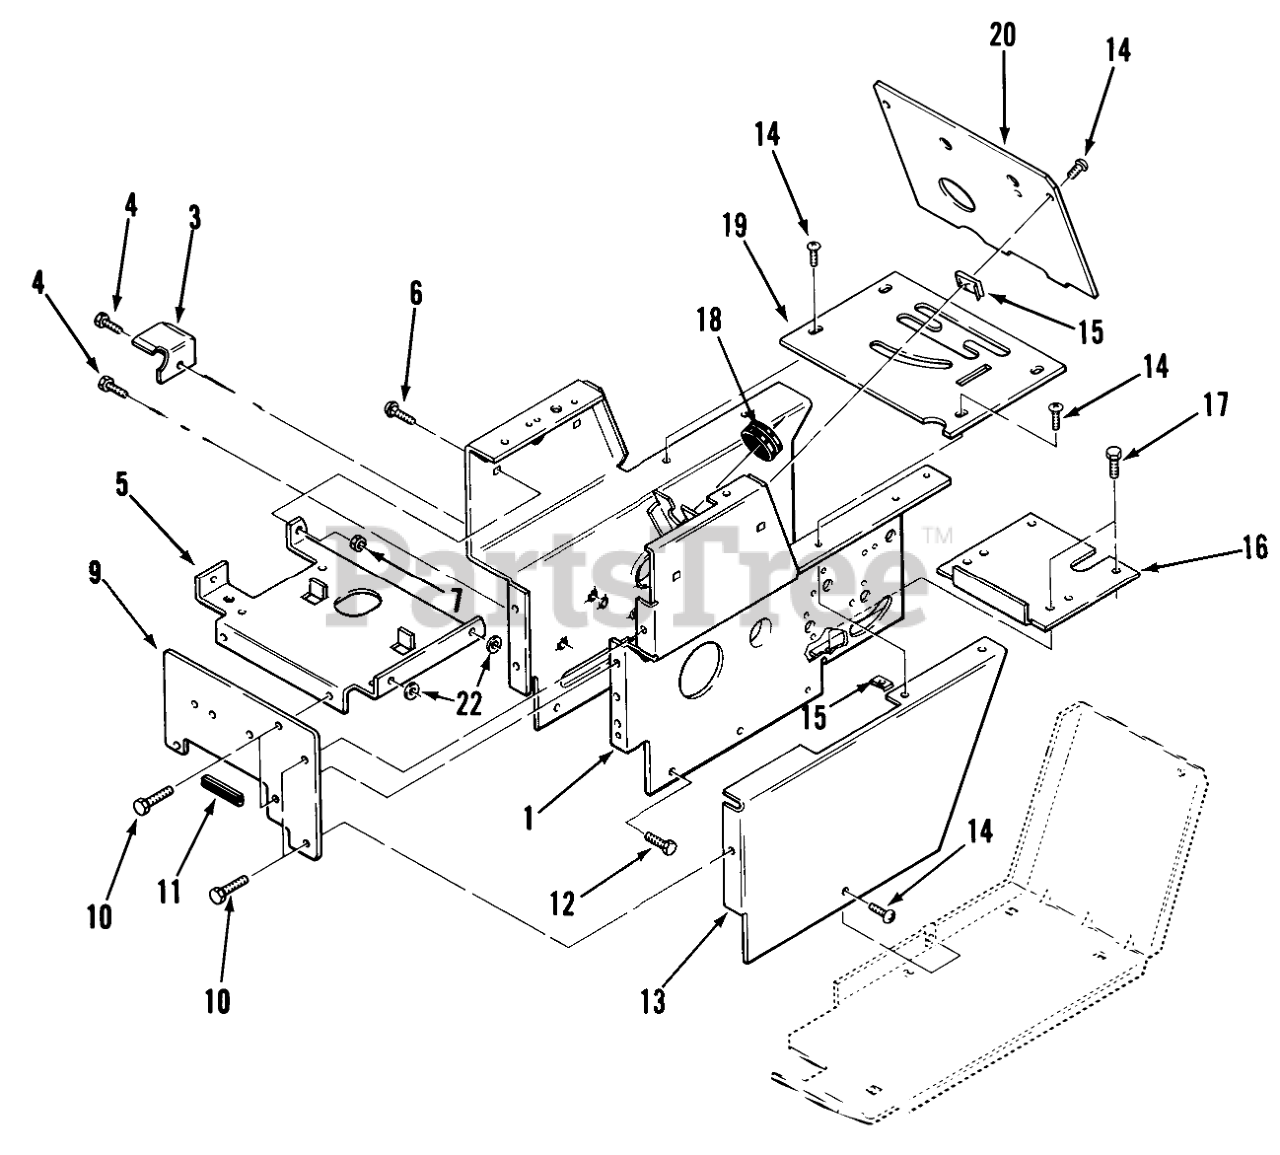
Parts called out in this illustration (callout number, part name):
1	Hoodstand
2	ANGL-BLT GURDB
3	BRCKET-BLT SUTB
3	Belt Bracket
4	SCREW
5	SUPPORT-BATTERY B
6	CARRIAGE BOLT -4
7	Nut
9	Front Plate
10	SCREW
11	EDGE TRIM 2" 102896
12	SCREW
12	Bolt
13	Side Cover LH
14	Screw
16	Cover-Dust
17	SCREW
18	GROMMET
19	Shift Cover Plate GT-1800 Only
19	Shift Cover Plate GT-1100, GT-1600 Only
20	Hoodstand Plate
20	Hoodstand Plate GT-1800 Only
22	WASHER 5/16 SAE
